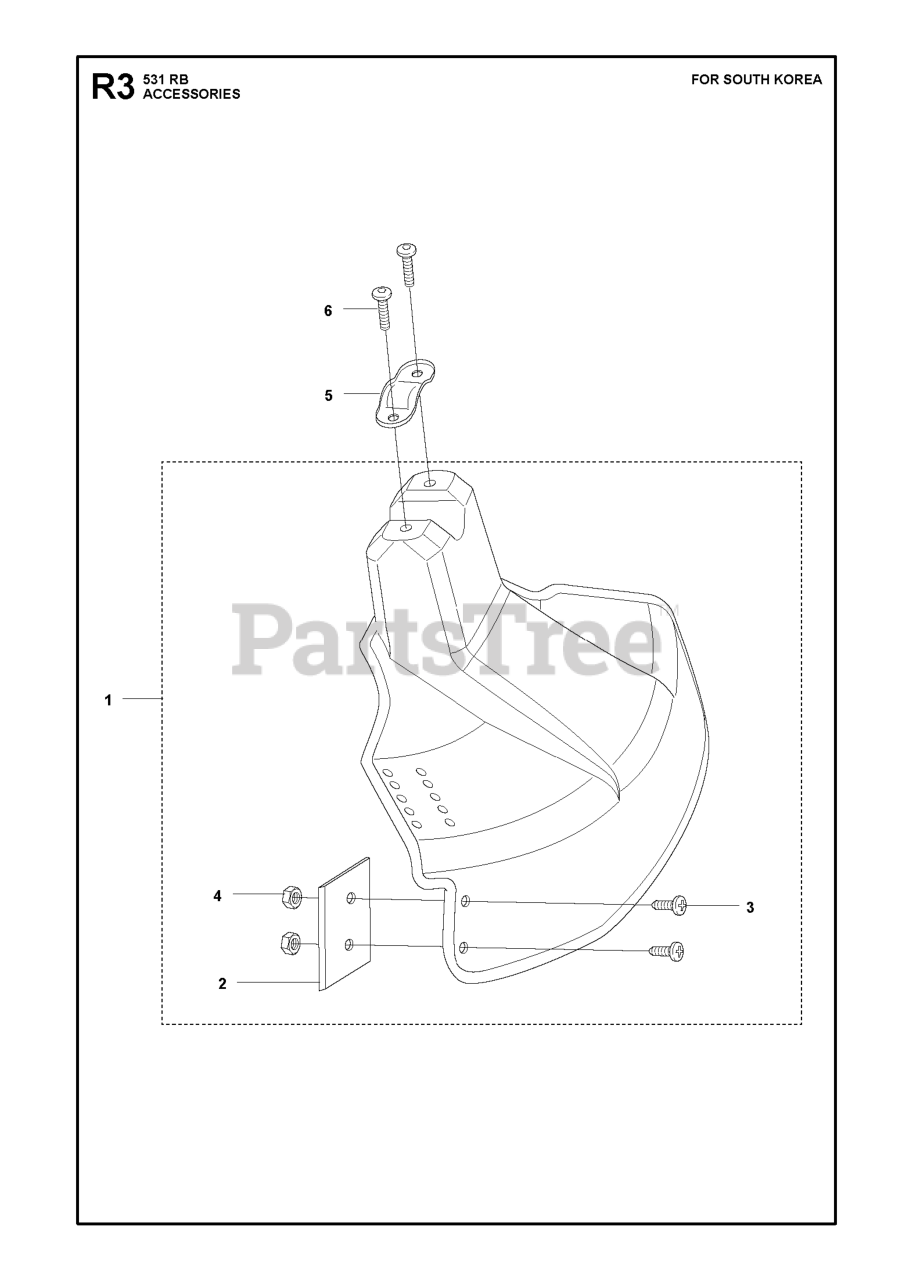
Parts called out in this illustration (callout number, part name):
3	SCREW
4	NUT
5	CLAMP
6	BOLT
